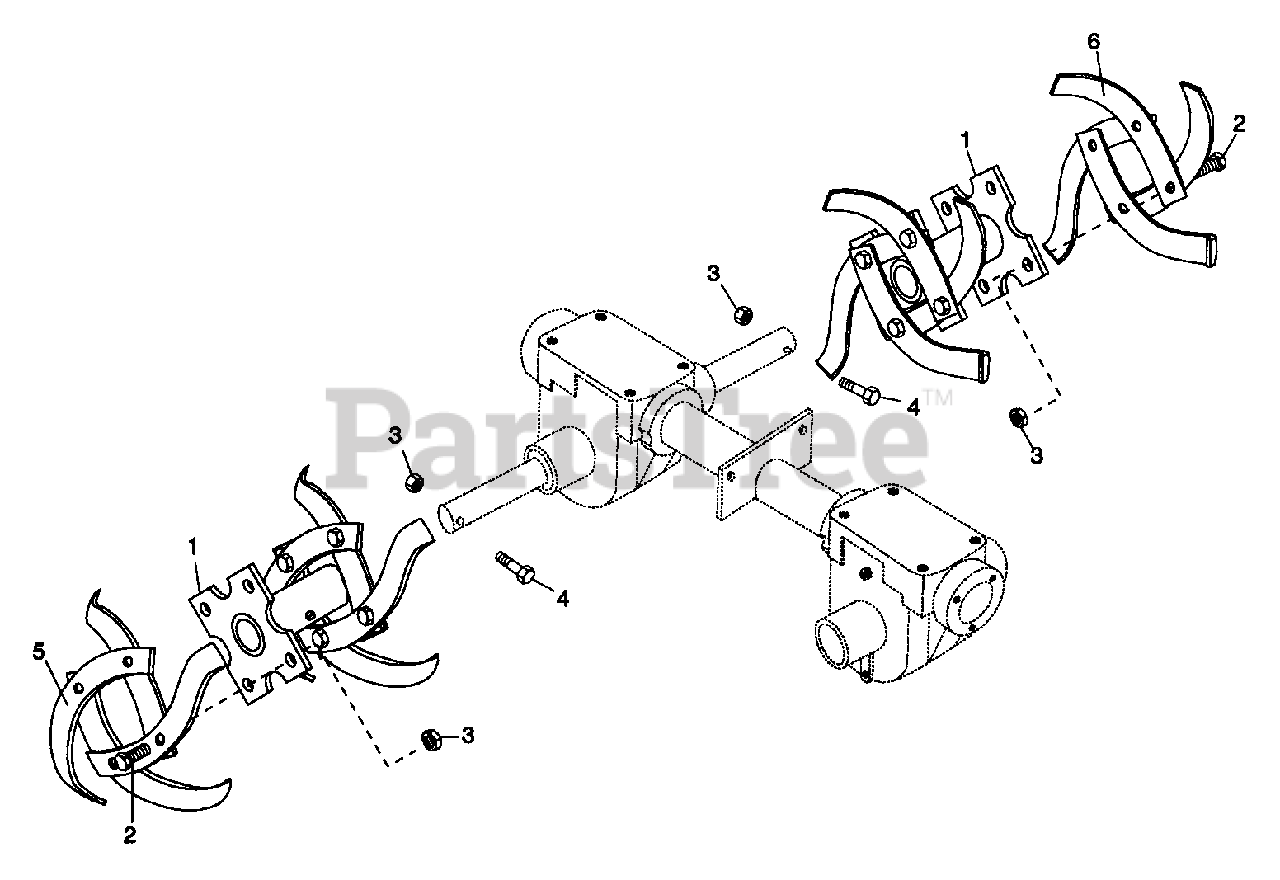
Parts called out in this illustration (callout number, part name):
1	HOLDER - BOLO TINE
2	BLT-HEX .38-16X1.00 PL GR5
3	NUT-LK-JAM-CTR .375-16 PL
4	SCR-CAP .38-16X1.75 GR8
5	RH BOLO TINE
6	LH BOLO TINE
